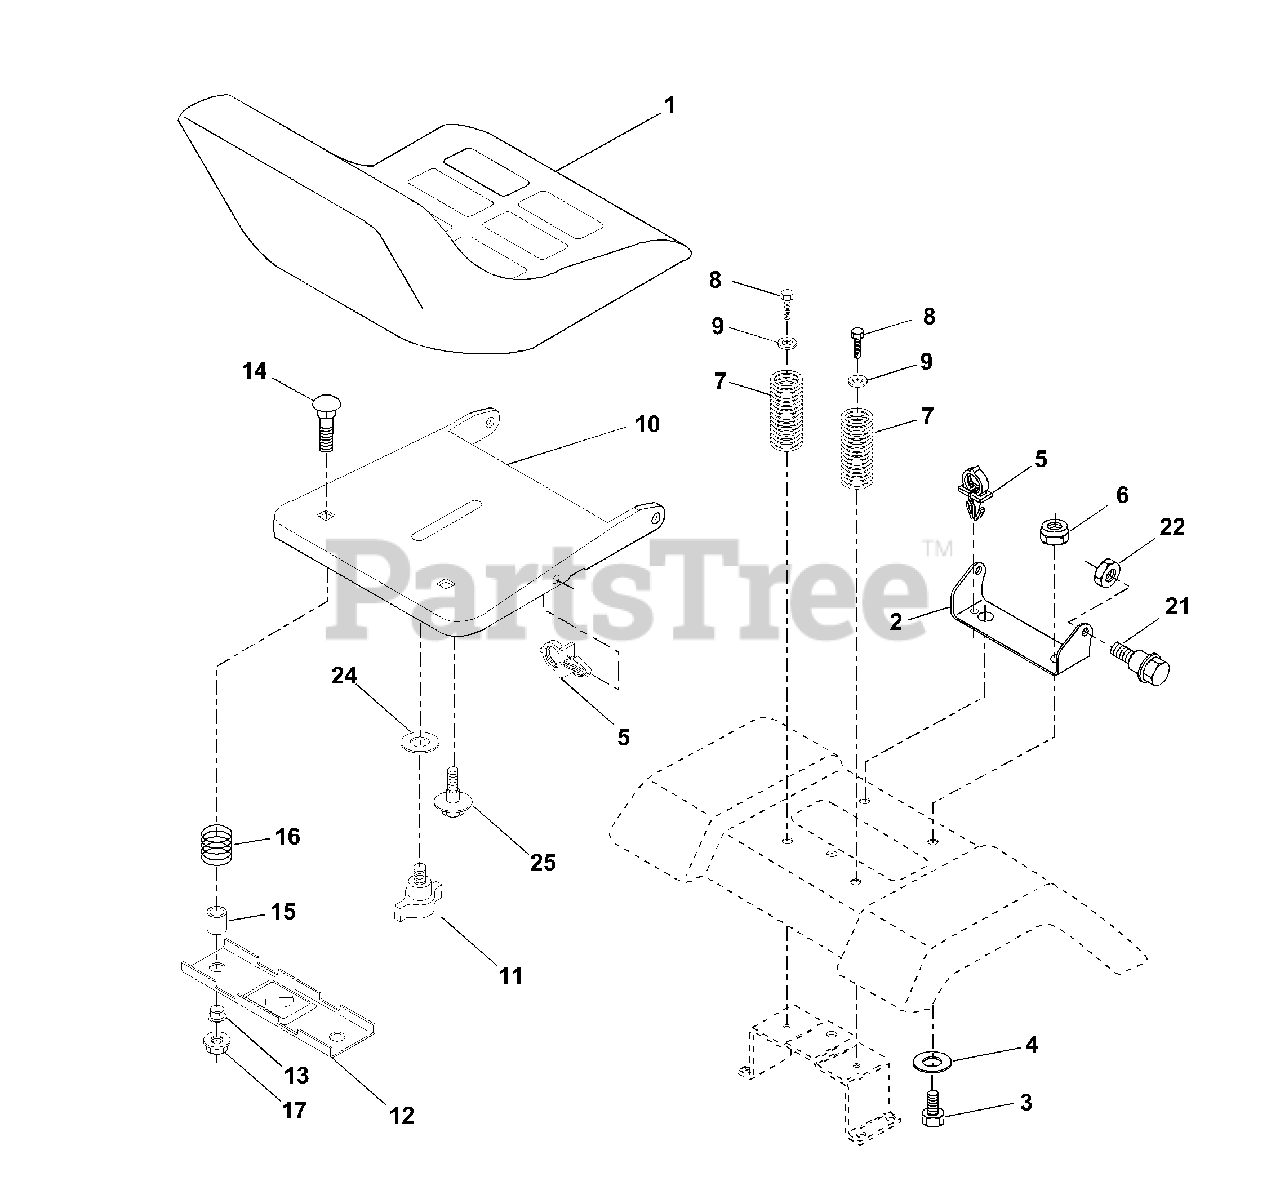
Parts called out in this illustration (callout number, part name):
1	Seat
2	Bracket Pivot Seat 8 720
3	Bolt Fin Hex 3/8-16unc X 1
4	Washer 13/32 X 1 X 10 Ga
5	Clip Push-In
6	Nut Hex w/Ins. 3/8-16 Unc
7	Spring Seat Cprsn 2 250 Blk Zi
8	Screw 3/8-16 x 1.5Smgml
9	Washer 13/32 X 1 X 14 Ga.
10	Pan Seat
11	Knob Seat
12	Bracket Mounting Switch
13	Bushing Snap Blk Nyl 50 Id
14	Bolt Rdhd Sqnk 1/4-20x1-1/2
15	Spacer Split 28x 88
16	Spring Cprsn
17	Nut Lock 1/4 Lge Flg Gr 5 Zinc
21	Bolt Shoulder 5/16-18 Unc
22	Nut Hex Lock W/Ins 5/16-18
24	Washer 17/32 X 1-3/16 X 12 Ga.
25	Bolt Shoulder 5/16-18 X 62
